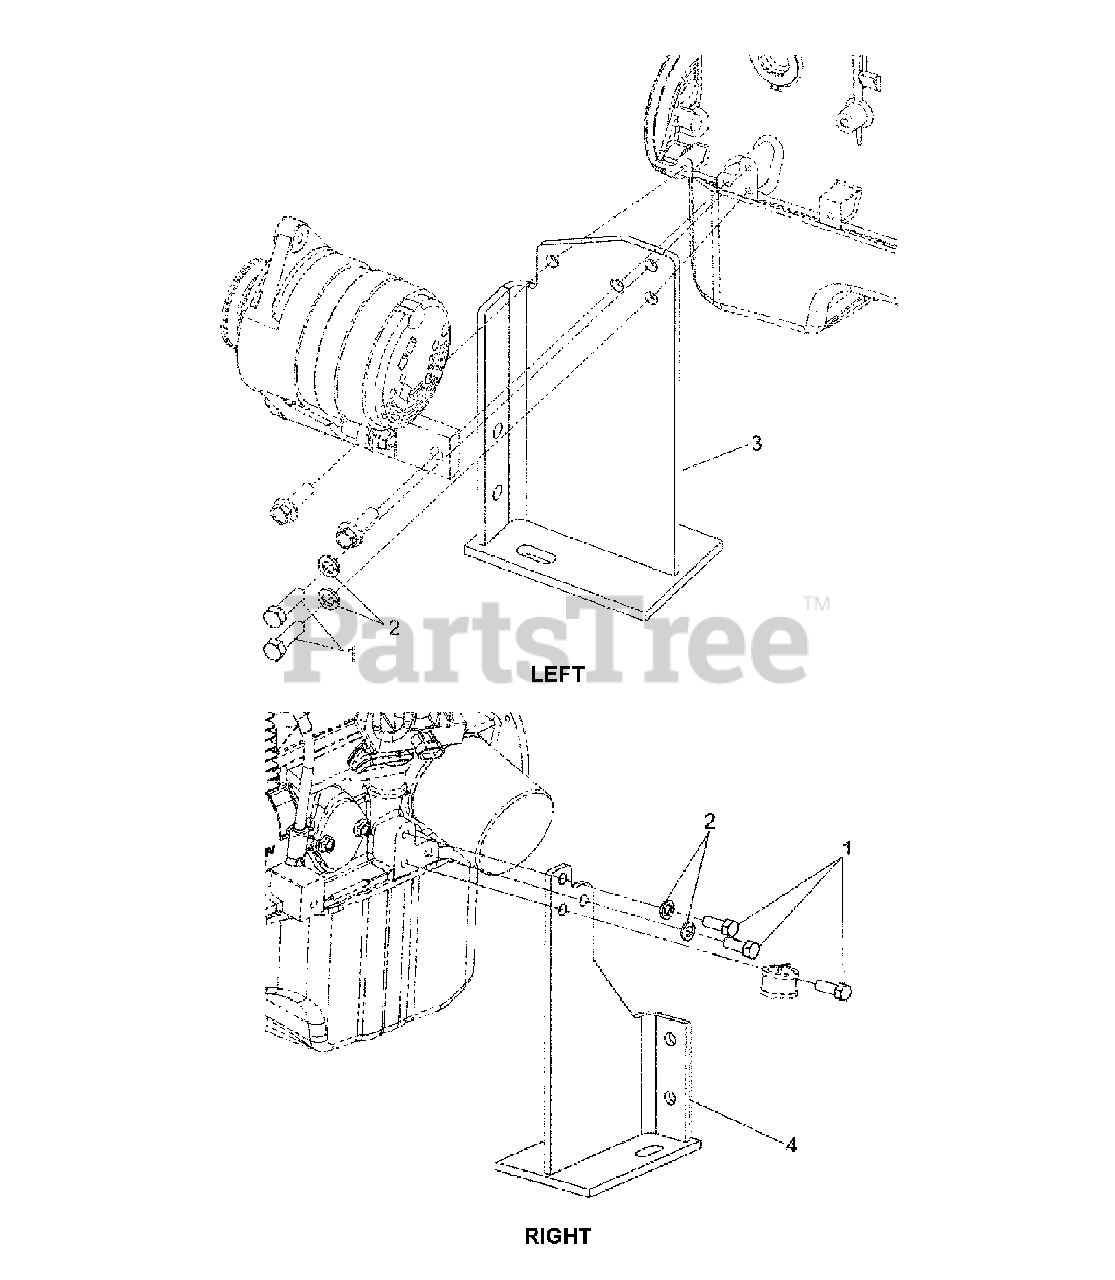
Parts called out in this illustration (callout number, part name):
1	BOLT
2	WASHER, Lock
3	BRACKET, Mount, LH
4	BRACKET, Mount, RH
